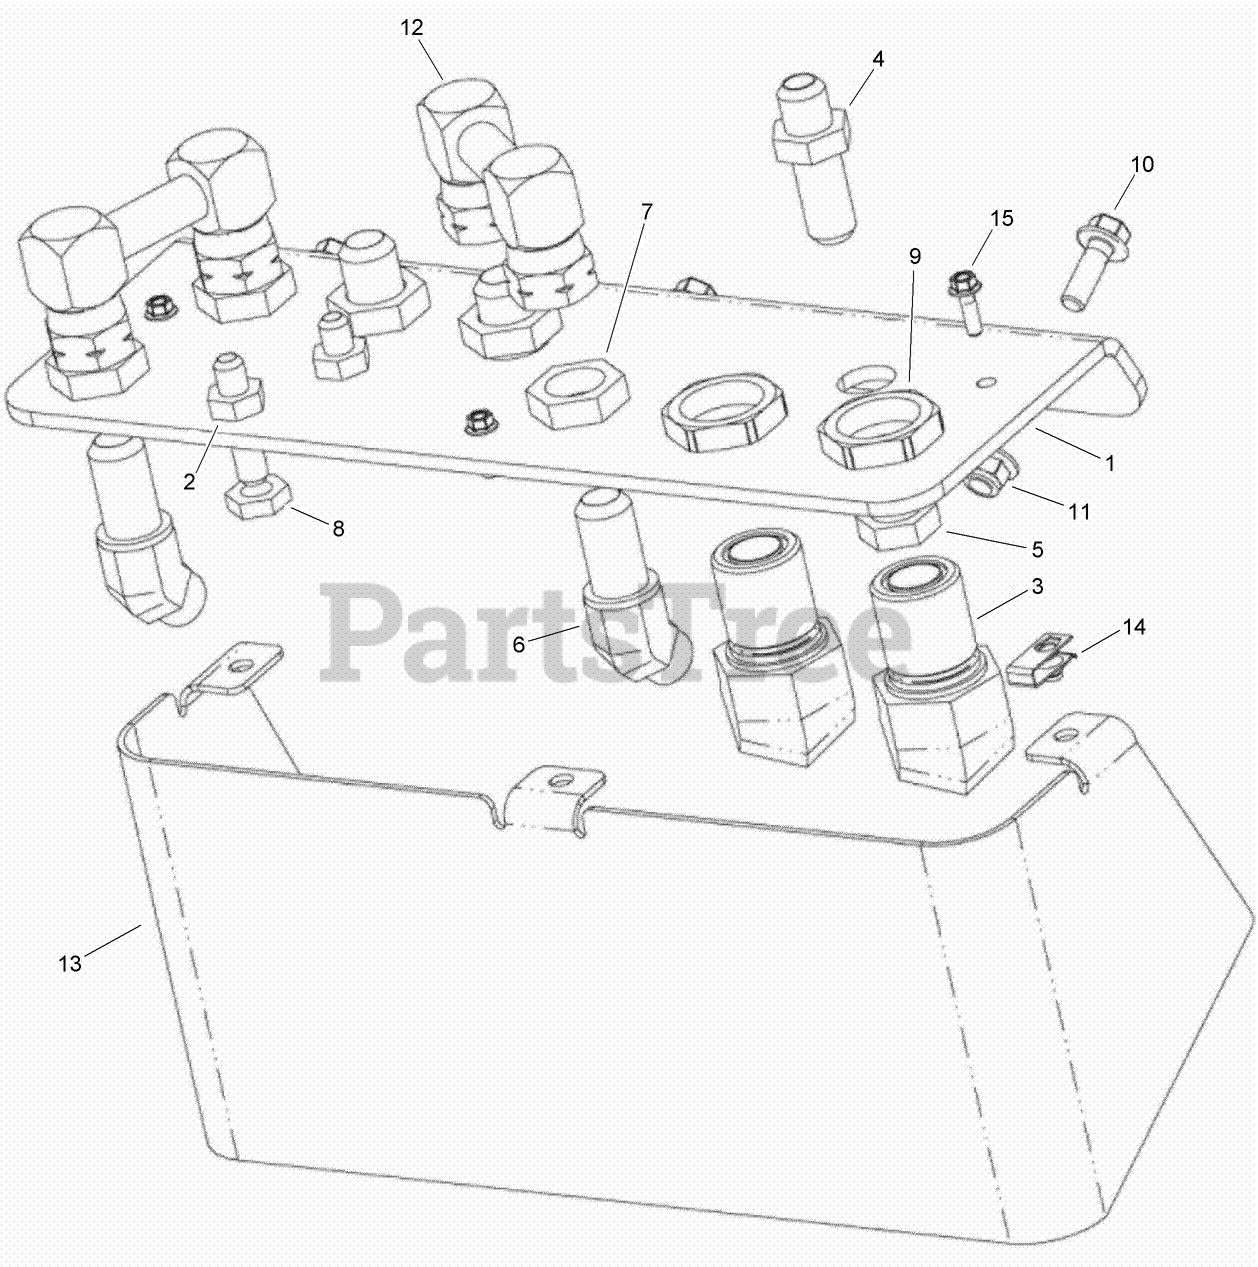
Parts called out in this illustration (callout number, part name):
1	PLATE-Bulkhead Mount
2	UNION-BULKHEAD
3	ELBOW-BULKHEAD, 45
4	UNION-BULKHEAD
5	NUT-LOCK, BULKHEAD
6	ELBOW-BULKHEAD, 45
7	NUT-LOCK, BULKHEAD
8	NUT-LOCK, BULKHEAD
9	NUT-LOCK, BULKHEAD
10	SCREW-HH
11	NUT-FLANGE, NYLOCK
12	FITTING-SPECIAL
13	PLATE-Cover
15	SCREW-HHF
